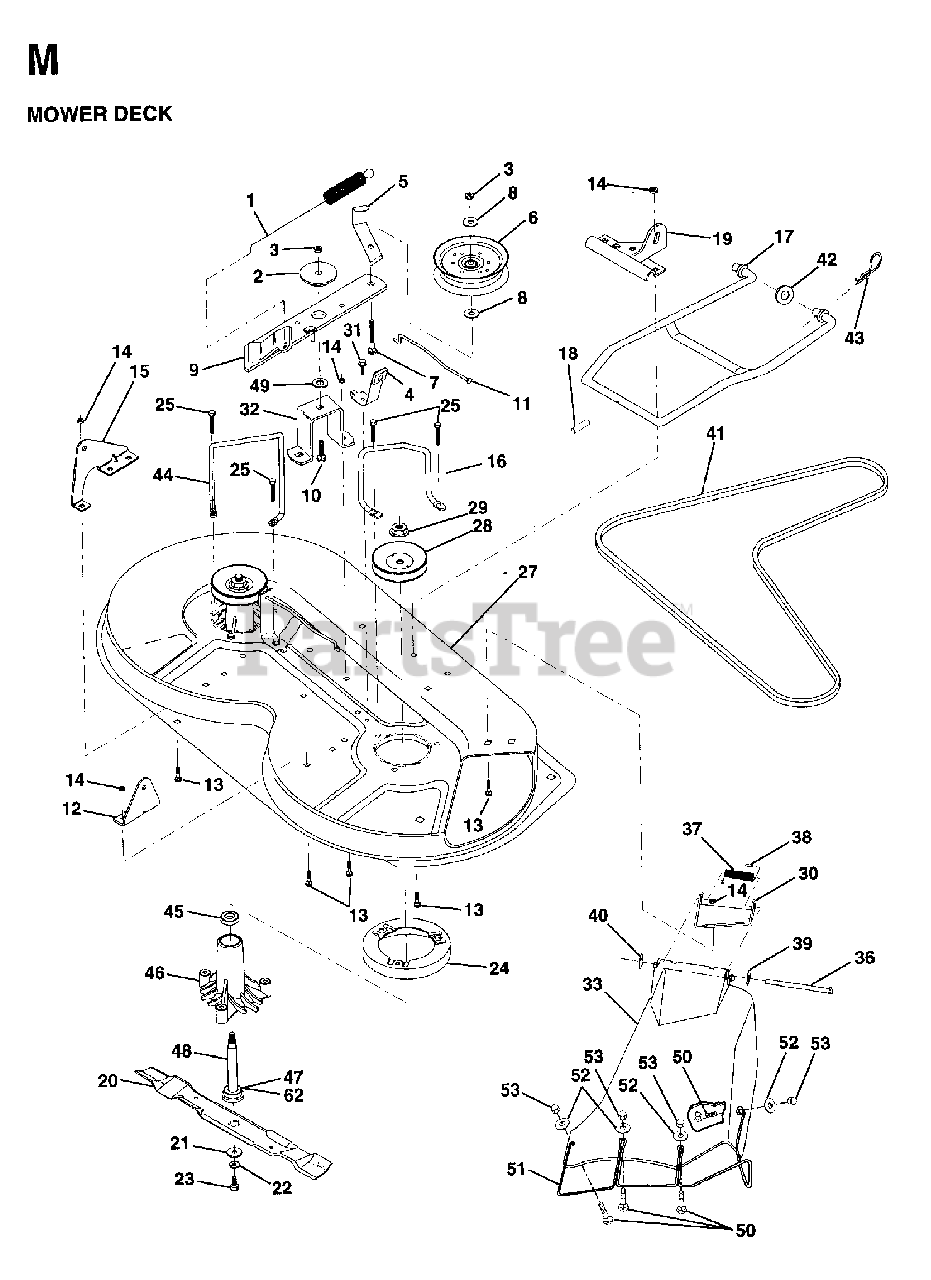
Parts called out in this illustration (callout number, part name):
1	SPRING-MOWER CLUTCH
2	SPACER RETAINER
3	LOCKNUT
4	BRAKE ASSEMBLY
5	IDLER BELT GUIDE
6	PULLEY IDLER
7	BOLT
8	WASHER
9	IDLER ARM ASSY
10	BOLT.3/8-14X1.25
11	BRAKE ROD
12	BRKT LIFT REAR
13	BOLT
14	LOCKNUT
15	BRKT LIFT REAR LH
16	BELT KEEPER
17	MOWER LINK STABILIZER
18	PIN GROOVE
19	BRKT LINK STABILIIZER
21	WASHER.BLADE
22	LOCKWASHER
23	BLADE BOLT
24	STRIPPER
25	SCREW
27	MOWER HOUSING
28	PULLEY, MANDREL
29	NUT
30	BRACKET ASM DEFLECTOR
32	SUPT,IDLER ARM
36	HINGE ROD
37	SPRING TORSION
38	CAP-SLEEVE LT
39	WASHER
40	NUT PUSH M
42	WASHER
43	SPRING RETAINER
44	KEEPER LH
46	HSG MANDREL
47	BEARING
48	SHAFT ASM VENT
49	HARDENED WASHER
50	SCREW
53	NUT
62	WASHER FELT
